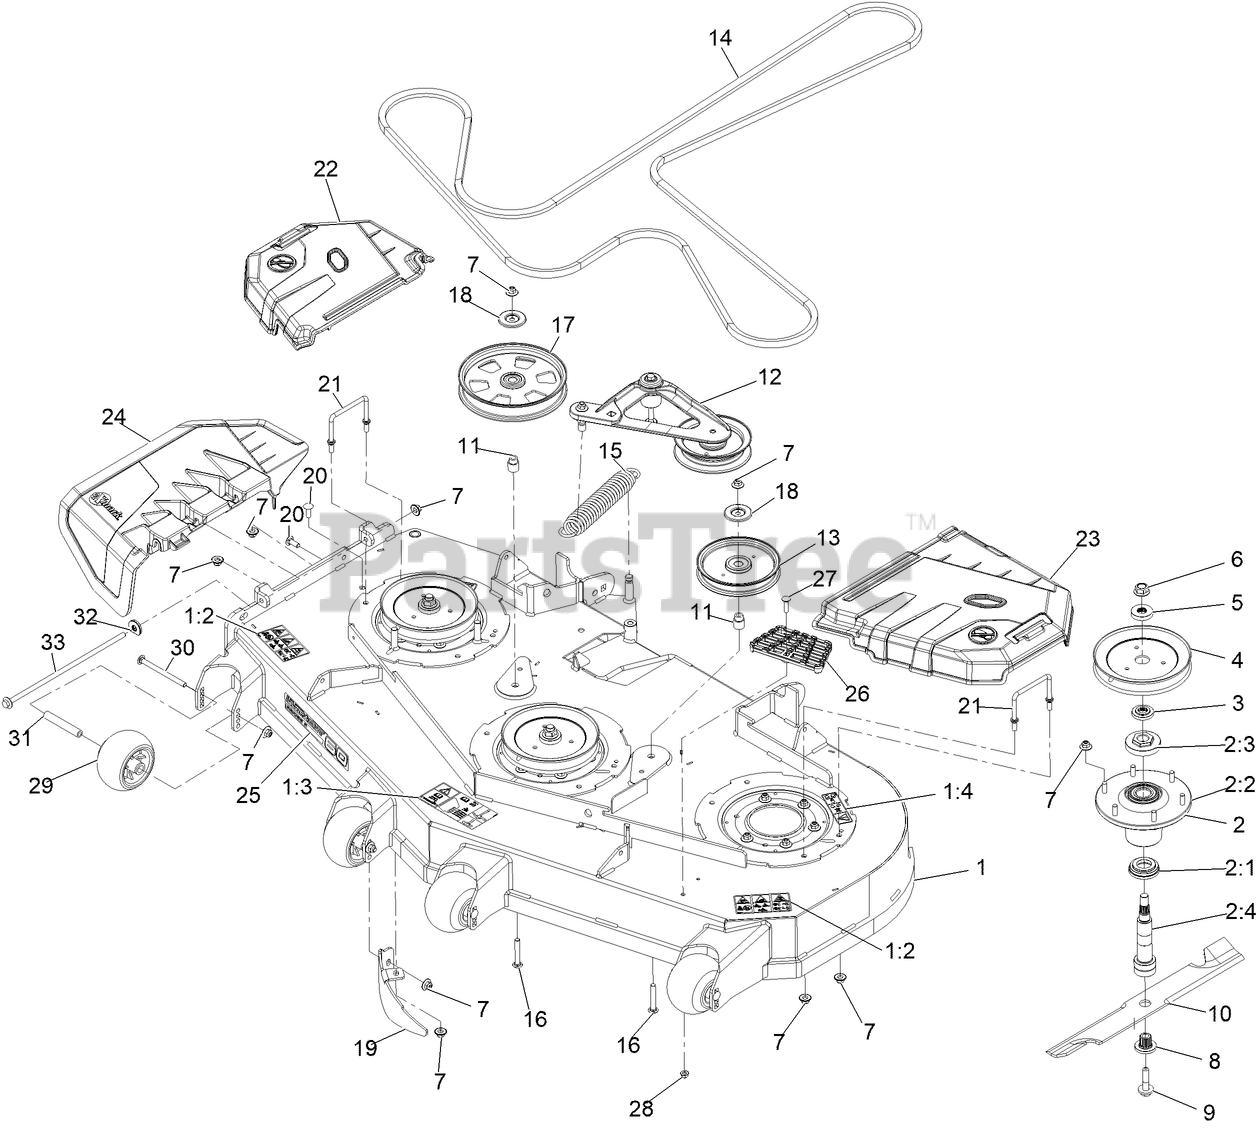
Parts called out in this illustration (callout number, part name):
1	Deck ASM, W/Decals 60
1:2	DECAL-DANGER THROWN OBJECTS
1:3	DECAL-ANTI-SCALP-BELT ROUTING
1:4	DECAL-COVER, MISSING
2	ASM,SPINDLE HOUSING
2:1	GUARD,BOTTOM
2:2	ASM,CUTTER HOUSING
2:3	NUT, SPINDLE 7/8-14
2:4	SPINDLE,DOUBLE SPLINE
3	SPACER,SPLINED STEPPED
4	SHEAVE-BLADE DRIVE 7.25
5	SPACER,SPLINED
6	NUT-FLANGE, CENTERLOCK
7	Nut-Nyloc 3/8-16 Flg
8	BUSHING,SPLINED
9	SCREW,SEMS 1/2-20 X 2.19
10	Blade-Extreme 2, 20.50"
11	BUSHING-IDLER
12	ASM-IDLER, DECK
13	Idler-Pulley, Flat
15	SPRING-EXTENSION
16	SCREW-CARR
17	PULLEY-IDLER, FLAT
18	SHIELD-DUST
19	DOGLEG - LZ60
20	SCREW-CARR
21	WIREFORM-COVER
22	SHIELD, RT
23	SHIELD, LT
24	Chute-Deck Discharge
25	DECAL, 606
26	STEP-DECK
27	Bolt-Carriage 5/16-18 X 1 1/4
28	NUT-HF, NI
29	ROLLER-SCALP, ANTI
30	BOLT-CARR
31	SPACER-AXLE
32	Retainer, Chute
33	Pin, Chute
